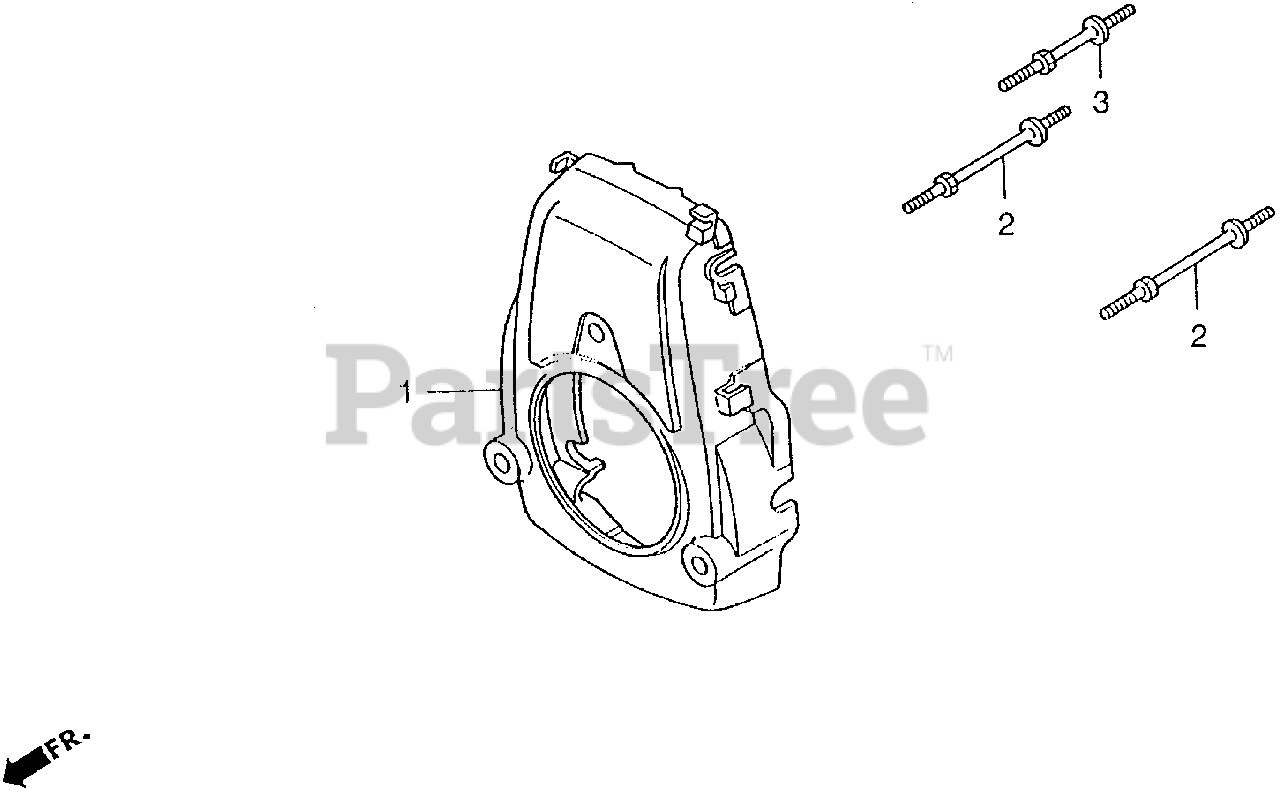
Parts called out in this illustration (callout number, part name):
1	COVER, FAN *R8* (BRIGHT RED)
2	BOLT A, STUD
3	BOLT B, STUD
